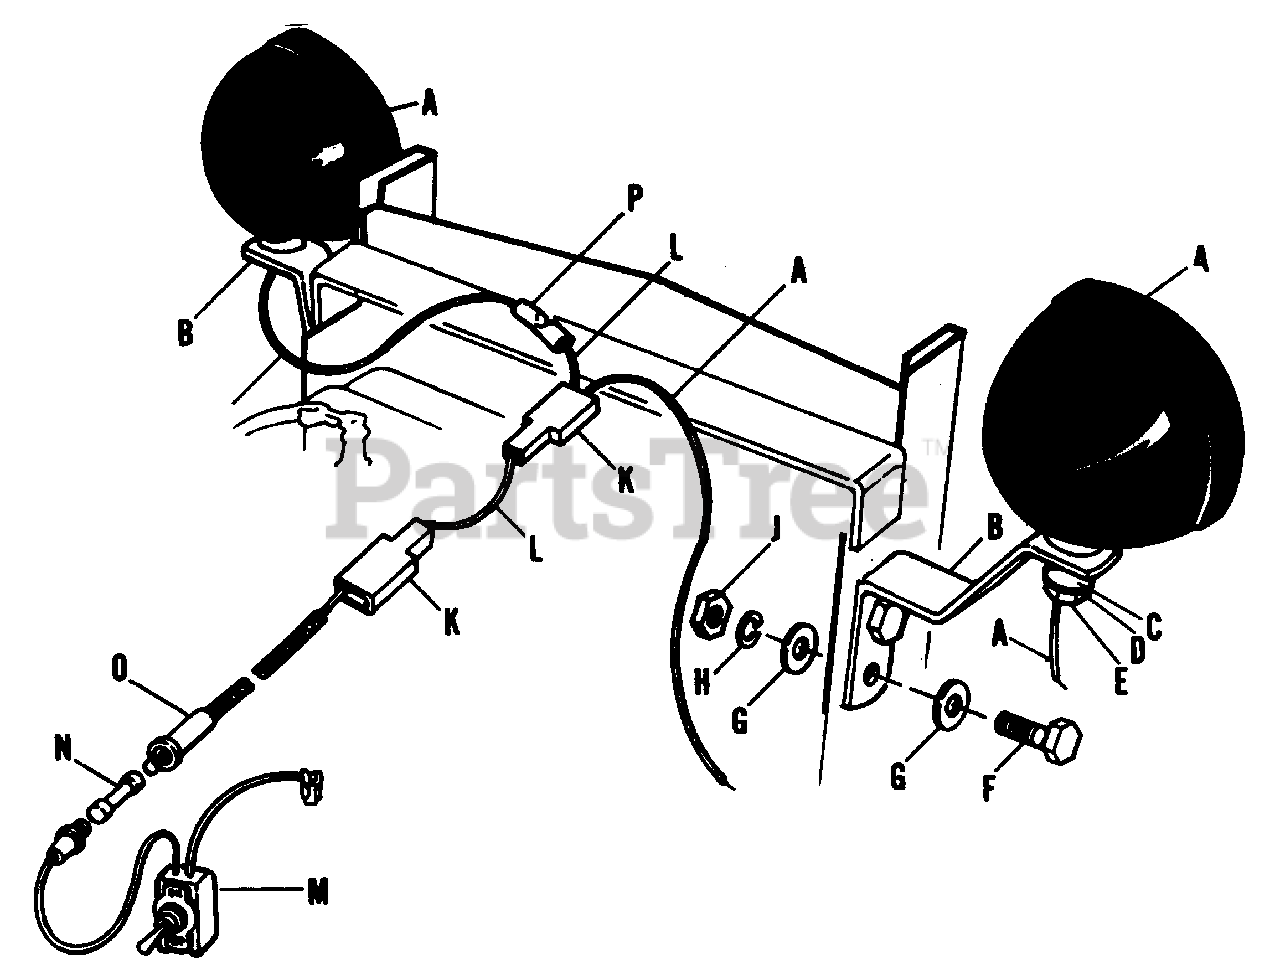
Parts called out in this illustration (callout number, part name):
A	Lamp Assembly
D	Lock Washer, 1/2"
E	Full Hex. Nut, 1/2"-13
F	Hex. Capscrew,5/16"-18 x 1-1/2"
G	Plain Washer, 5/16"
H	Lock Washer, 5/16"
J	Full Hex. Nut, 5/16"-18
K	Insulated Connector
L	Extension Wire
M	Toggle Switch (with hardware)
N	Fuse 20 Amp.
O	Wire Connector
P	Connector
